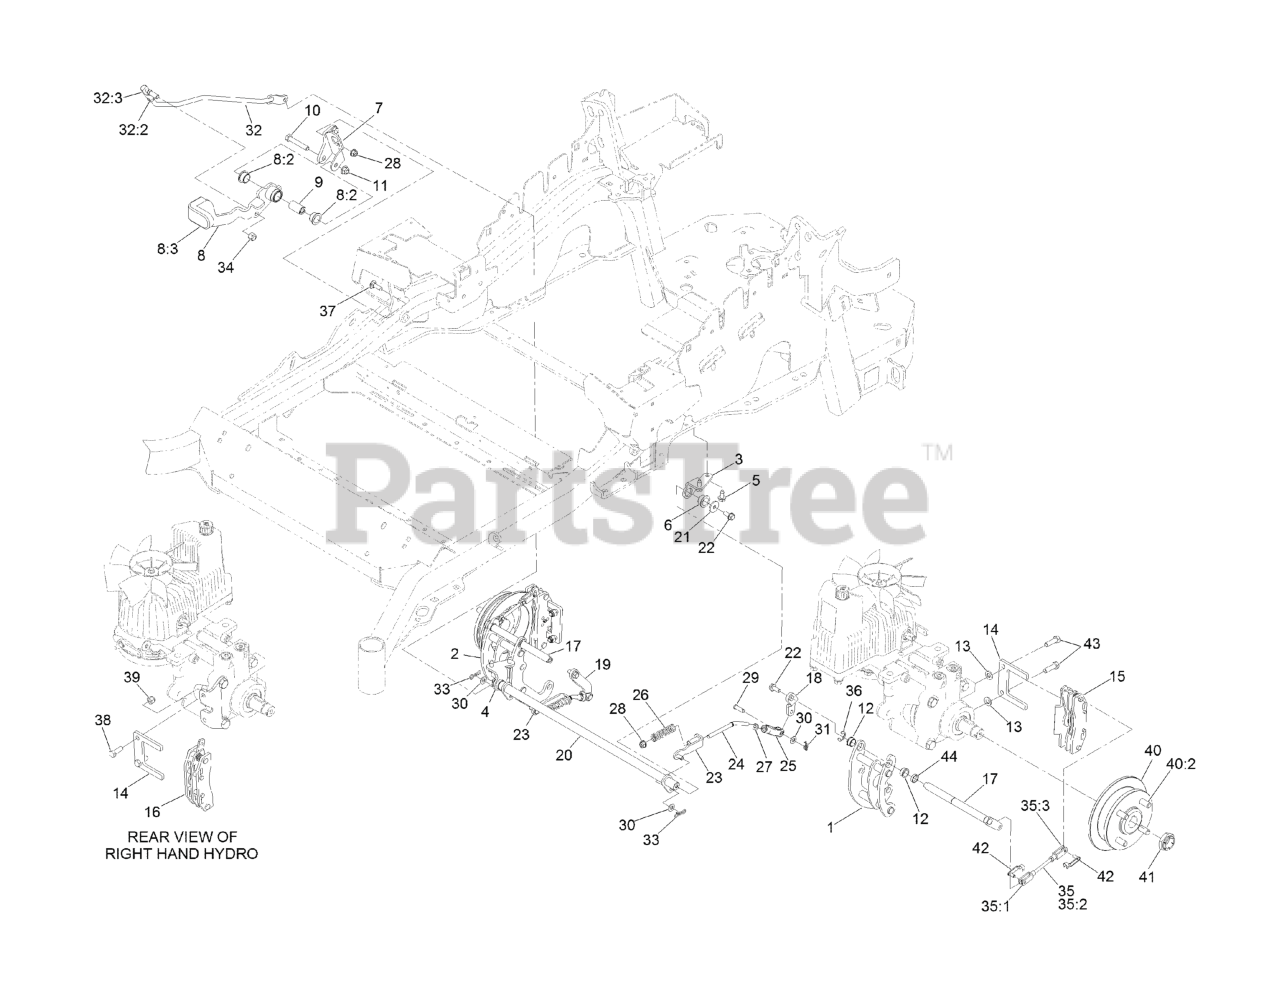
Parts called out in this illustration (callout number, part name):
1	MOUNT-BELLCRANK, LH
2	MOUNT-BELLCRANK, RH
3	MOUNT-PIVOT, LH
4	MOUNT-PIVOT, RH
5	Screw-HWH 5/16-18 X 3/4 Tf
6	BUSHING-FLANGE
7	BRACKET-MOUNT
8	BRAKE LEVER ASM W/ GRIP
8:2	BUSHING-FLANGE
8:3	GRIP-LEVER
9	HANDLE-PIVOT, BRAKE
10	SCREW-HH
11	NUT-HF, NI
12	BUSHING
13	WASHER-FLAT
14	PLATE-MOUNT, BRAKE
15	CALIPER-BRAKE
16	CALIPER-BRAKE, RH
17	BELLCRANK
18	ARM-INNER, LH
19	ARM-INNER, RH
20	SHAFT-CROSS
21	WASHER-FLAT
22	SCREW-HHF
23	BRACKET-L
24	LINKAGE-MID
25	YOKE-OFFSET
26	SPRING-COMPRESSION
27	NUT-JAM
28	NUT-HF, NI
29	PIN-CLEVIS
30	WASHER-PLAIN
31	PIN-COTTER, LOCKING
32	FRONT LINKAGE ASM
32:2	END-TIE ROD, RH
32:3	NUT-HJ
33	PIN-COTTER, LOCKING
34	NUT-LOCK
35	REAR LINKAGE ASM
35:3	NUT-JAM
37	BOLT-CARR
38	SCREW-HH
39	NUT-LOCK, NI
40	WHEEL HUB ASM
40:2	STUD-WHEEL
41	LOCKNUT
42	PIN-CLEVIS, SPRING
43	SCREW-LOCK, PATCH
